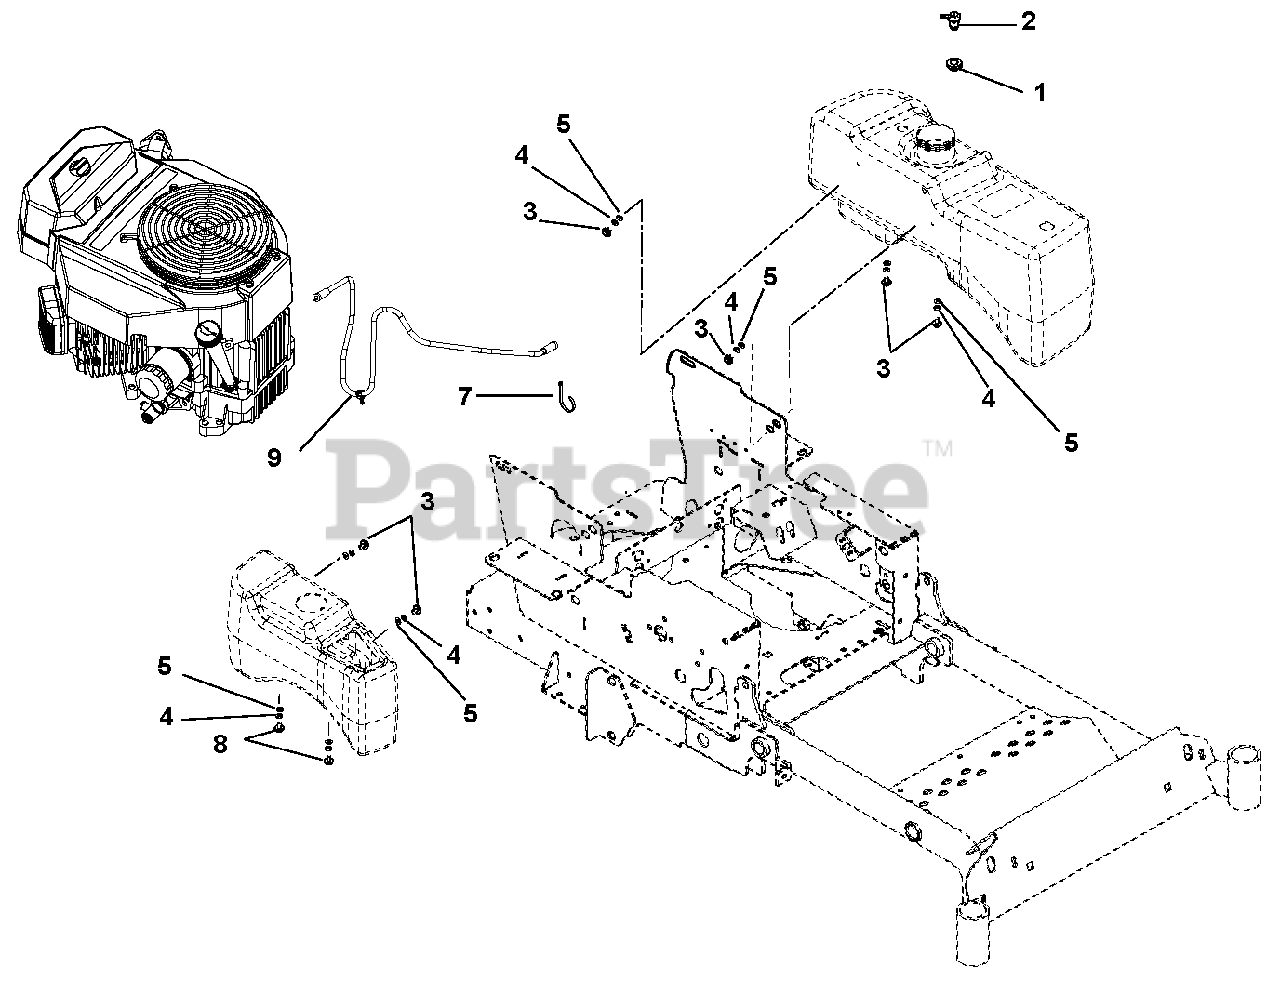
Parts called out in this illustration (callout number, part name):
2	Valve
3	Bolt, .31-18 x .62
4	Washer, Locking .31 x .078 Regular
5	Washer, Flat Steel .38 x .875 x .083
6	Cupholder, Snap-in 3.75 O.D.
7	Tie, Cable LG 5.50
8	Screw, Plastite .25-10 x .75 YZ
9	Line, ZTHD Kawasaki Evap
